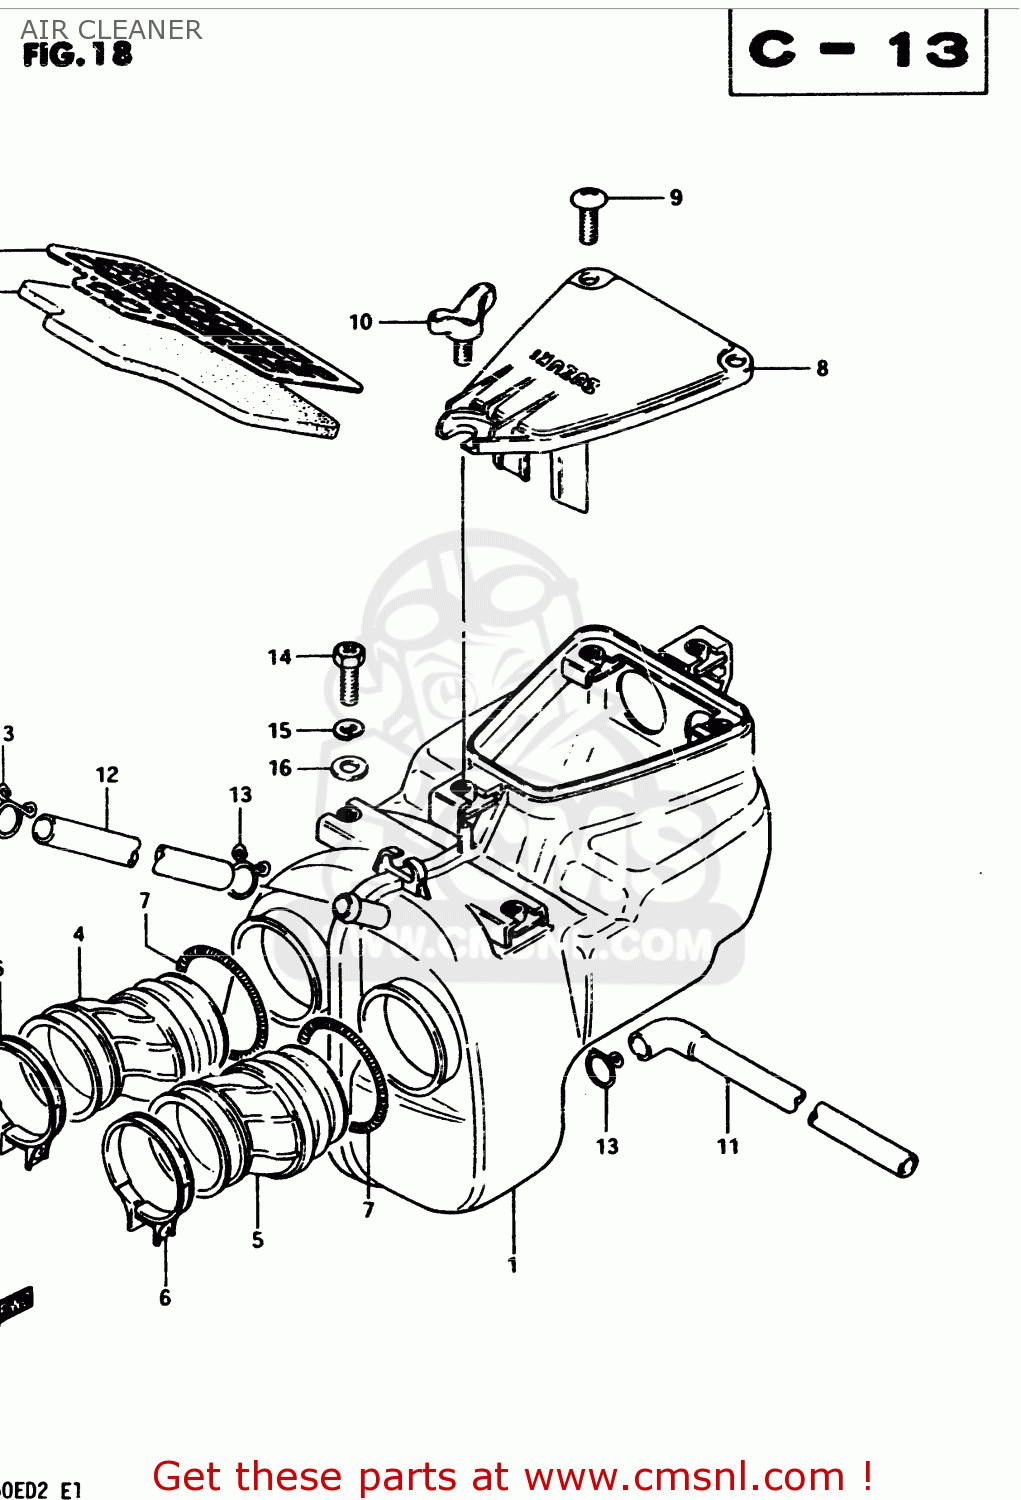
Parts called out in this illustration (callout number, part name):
1	CLEANER ASSEMBLY,AIR
2	FILTER
3	HOLDER,OUTER
4	TUBE,OUTLET,R
5	TUBE,OUTLET,L
6	CLAMP
7	CLAMP,CLEANER SIDE
8	CAP,AIR CLEANER
9	SCREW
10	BOLT, WING
11	DRAIN TUBE
12	TUBE,BREATHER
13	CLAMP
14	SCREW(6X12)
15	LOCK WASHER
16	WASHER
